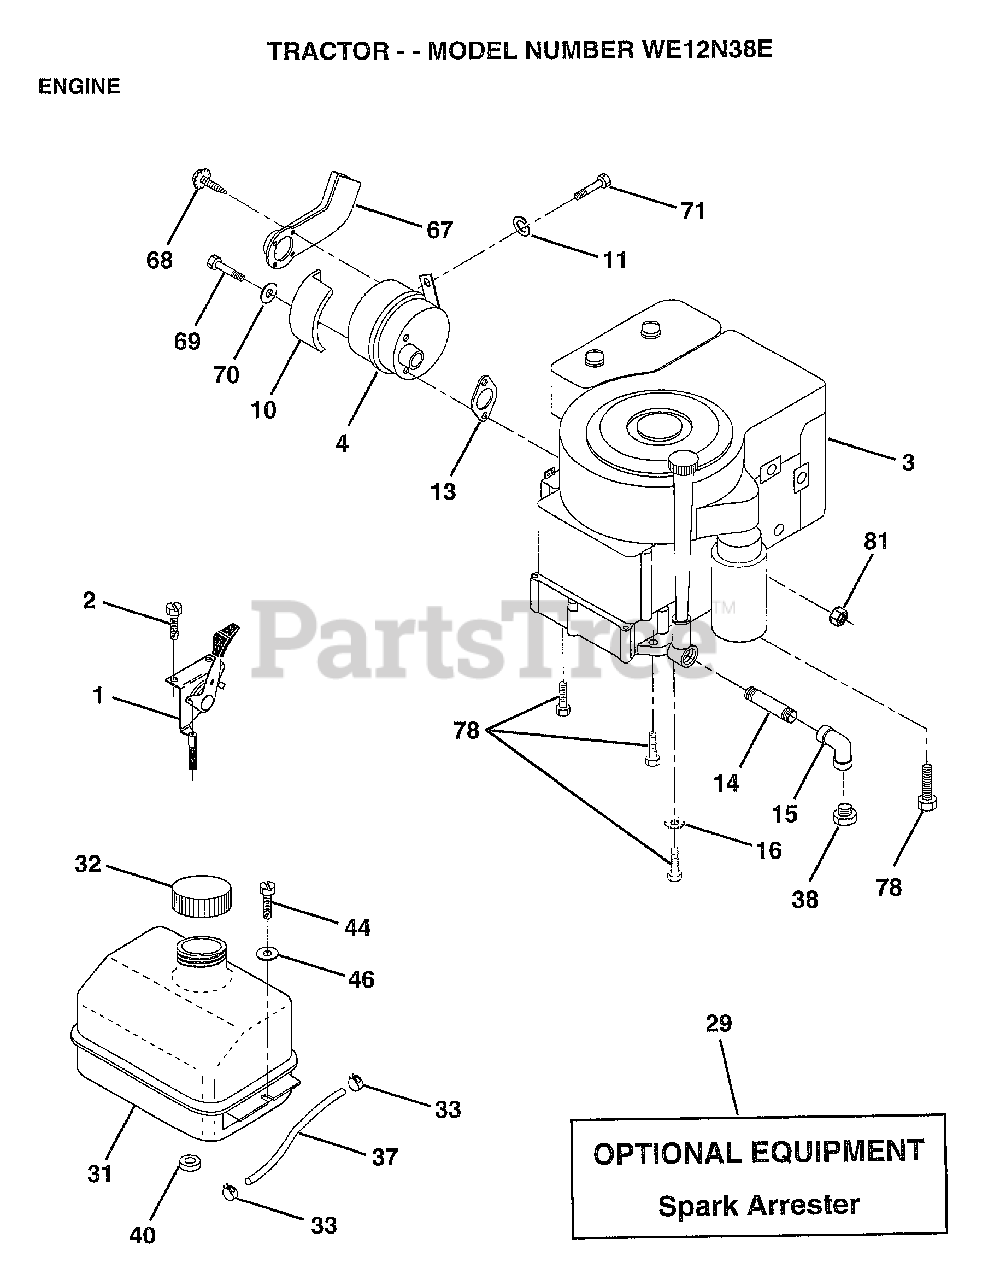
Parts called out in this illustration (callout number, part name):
1	THROTTLE CONTROL
2	SCREW LT
4	MUFFLER LTV
10	SHIELD HEAT LTV
11	LOCKWASHER
13	GASKET ENG 1 313 LD TIN PLATED
14	PIPE NIPPLE
15	ELBOW
16	LOCKWASHER
31	TANK.FUEL.LT.
32	CAP ASM FUEL
33	HOSE CLAMP
37	LINE FUEL
44	SCREW HEX CRT
46	WASHER
67	DEFLECTOR MUFFLER
69	"BOLT,HEX"
70	WASHER T
71	BOLT HXHD FIN
78	SCREW
81	NUT
